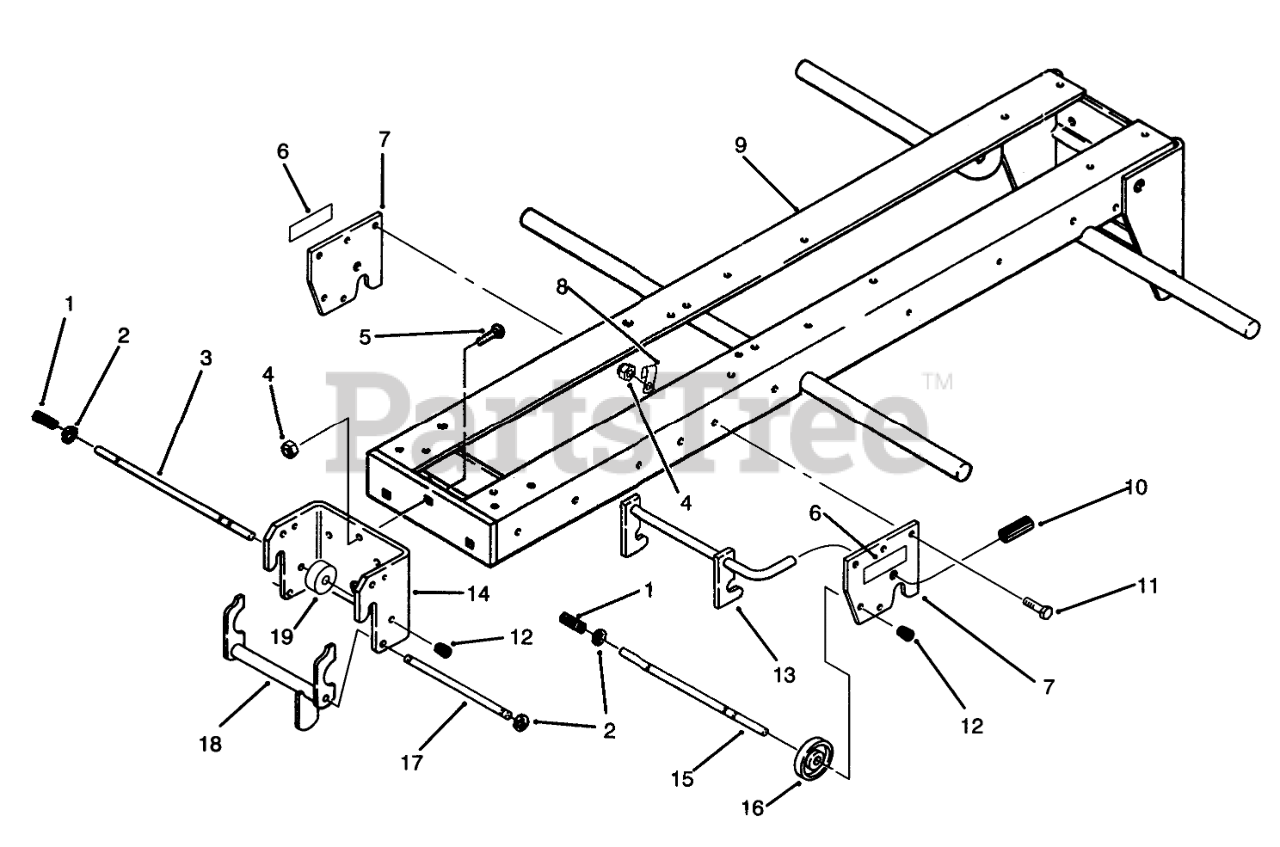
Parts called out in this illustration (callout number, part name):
1	SPRING
2	RING-RETAINING
3	ROD-LOCK
4	NUT-LOCK, NI
5	BOLT-CARR
6	DECAL-ATTACH A-MATIC
7	Hitch Plate
8	CLIP
9	WELD FRAME R
10	GRIP
11	SCREW-HH
12	CAP-ROD, PLUNGER
13	MID HITCH ASM
14	Front Hitch
15	ROD-LOCK
17	ROD-LATCH PIVOT
18	LATCH
